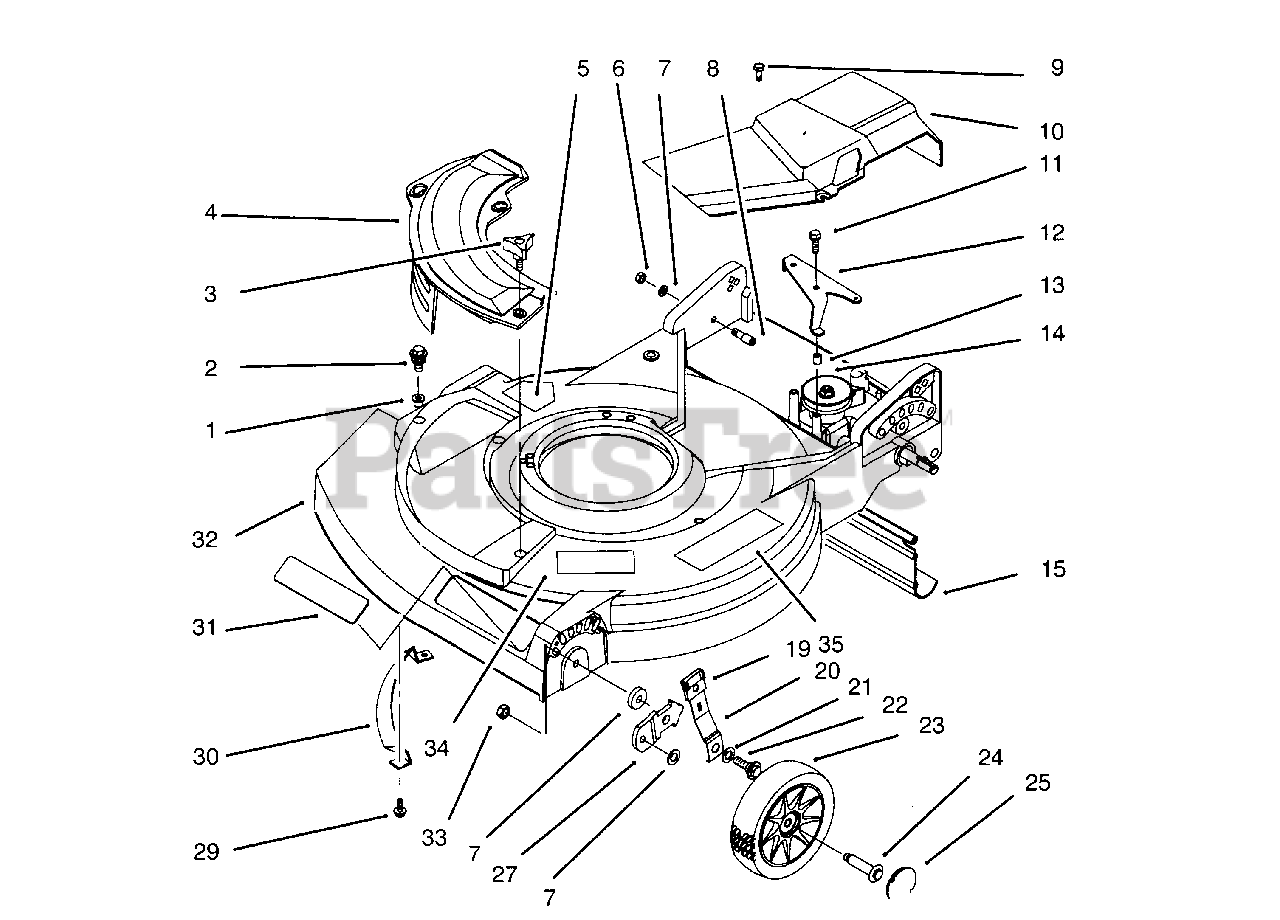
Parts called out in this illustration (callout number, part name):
1	Grommet
2	Screw-Thread Forming
3	Knob
4	Cover-Plate, Mulch
5	Decal-Danger (English)
7	Washer-Wheel
8	Bolt-Shoulder
10	Cover-Drive
11	Screw
12	Bracket-Actuator
14	Gear Case Assembly
15	Shield-Trailing
19	Knob-Spring Arm
20	Spring Arm Assembly
21	Washer-Belleville
22	Bolt-Shoulder
23	Wheel-6"
24	Bolt-Wheel
27	Bracket-H.
30	Bar-Toe
31	Applique
32	Housing-21 (Incl. Ref. #5 & 31)
33	Nut-Lock
34	Decal-No Rust
35	Decal-Warning
